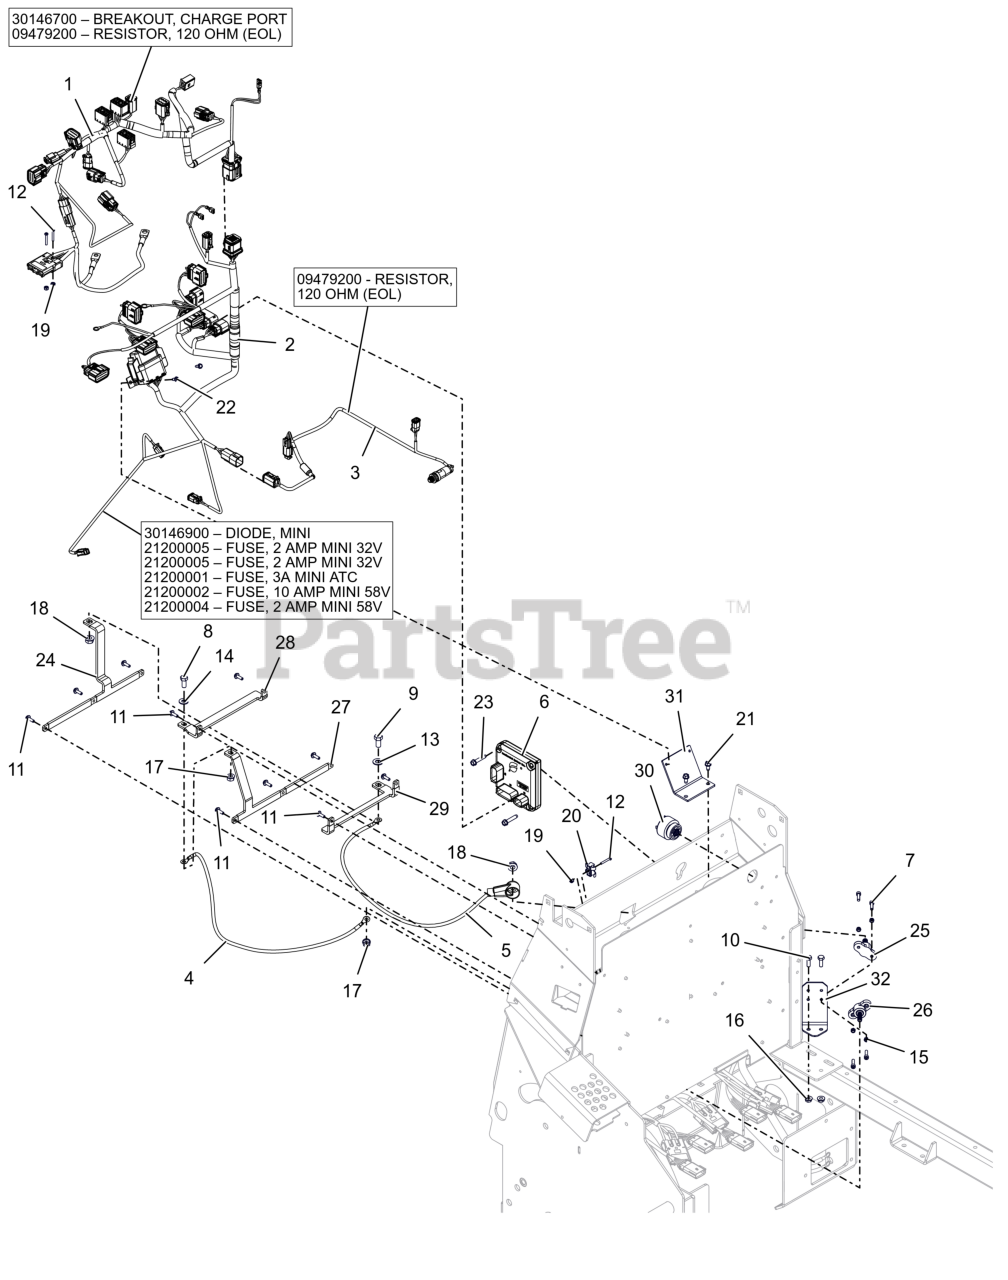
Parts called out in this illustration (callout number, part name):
1	HARNESS, ELECTRICAL -PSEV
1	BREAKOUT, CHARGE PORT
1	RESISTOR, 120 OHM (EOL)
2	HARNESS, ELECTRICAL -PSEV
2	DIODE- MINI
2	FUSE- 2 AMP MINI 32V
2	FUSE, 3A MINI ATC
2	FUES, 10 AMP MINI 58V
2	FUSE- 2 AMP MINI 58V
3	HARNESS, ELECTRICAL -PSEV
3	RESISTOR, 120 OHM (EOL)
4	CABLE, NEG 26"
5	CABLE, POS 26"
6	VCM, RD ASSY
7	SCR, SKH M5-.8 X 20 GR12.9 ROHS
8	BLT,HEX .31-18X.75 G5 ZCC
9	BLT,HEX .38-16X.75 G5 ZCC
10	BLT, HEX .25-20X.75 G5 ZCC
11	BLT,HEX M5-.8X16 EP30 G8.8 ZCC
12	SCR, PH PAN HD #6-32X1.000 ZCC
13	WSHR, FLT .406X.812X.065 RAW
14	WSHR, FLT .312X.734X.065 ZCC
15	NUT, LK-NYL M5-0.8 GR8.8 ZC120
16	NUT-LK-CTR-FLG .25-20 ZC120
17	NUT,LK-CTR-FLG .31-18 GF ZCC
18	NUT-LK-CTR-FLG .375-16 GF ZCC
19	@NUT-LK-NYL 6-32 W/INSRT YWZC
20	CLIP,T,.31-.38,
21	SCR-TAP .25-20X.50 HWH ZCC
22	SCR,TAP #10-24X.50 HWH TR ZCC
23	SCR-TAP .25-20X1.25 HWH TR ZCC
24	BAR, BUSS-POS
25	STUD, POSITIVE POWER
26	STUD, NEGATIVE POWER
27	BAR, BUSS -NEG
28	BAR, BUSS-NEG. WHL
29	BAR, BUSS -POS. WHL
30	ALARM- AUDIBLE
31	BRKT, FUSE BLOCK MTG (ORANGE)
32	BRKT- BATTERY TERMINAL
